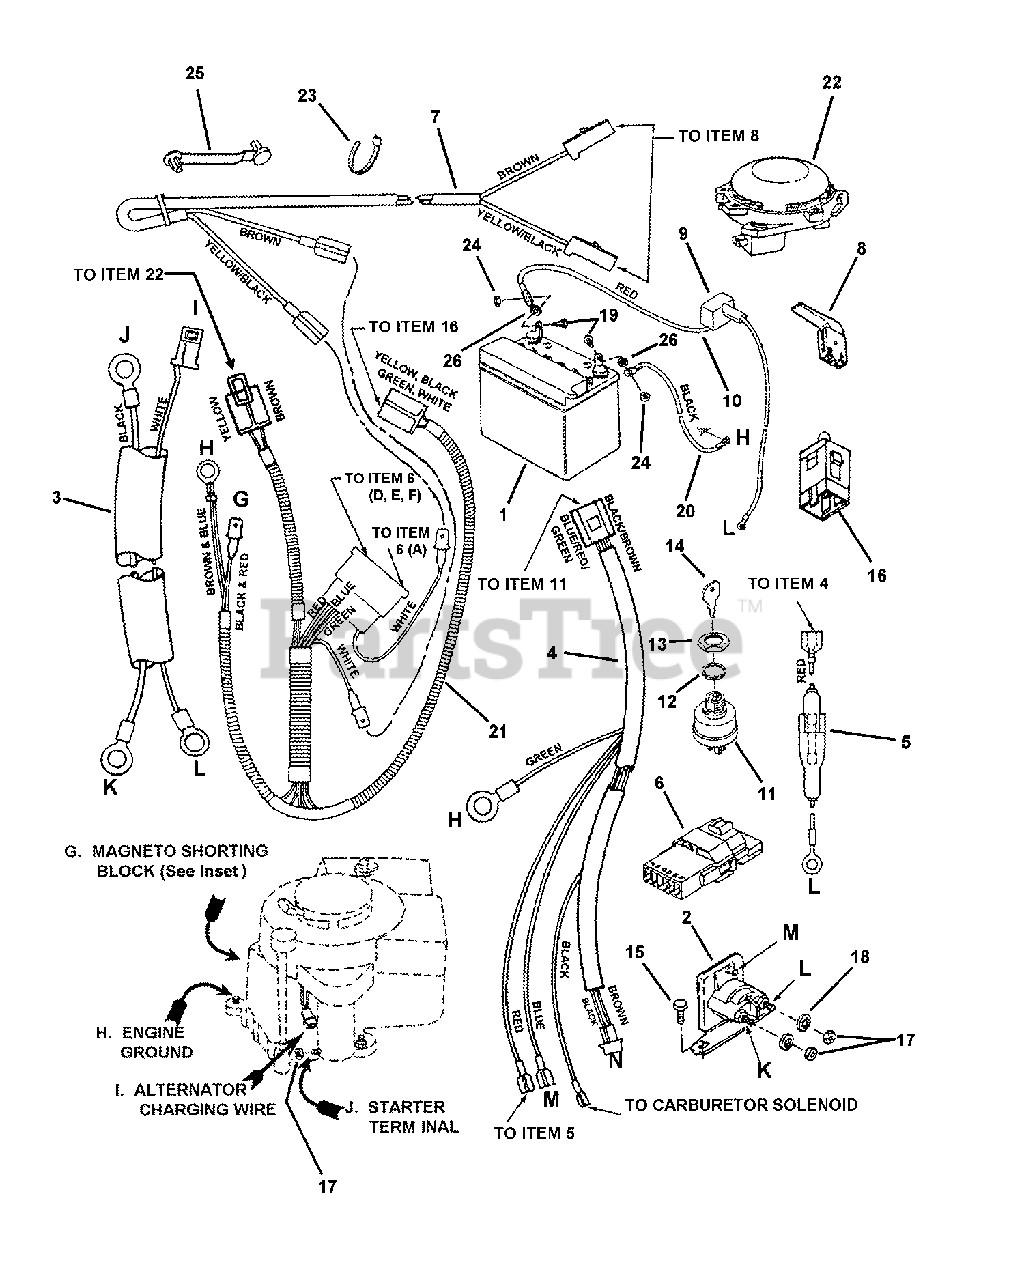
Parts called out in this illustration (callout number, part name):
1	KIT, Battery, 12V, U-1-7RS, 220CCA Dry Charge Snapper No Spill
2	SOLENOID, Super-Trombetta
3	HARNESS, Starter Wiring (Briggs Engines)
4	HARNESS, Ignition Wiring (Briggs)
5	HOLDER, Fuse (Includes Fuse)
6	INTERLOCK MODULE, Briggs
7	HARNESS, (Deck Interlock Wiring)
8	SWITCH, Deck Interlock (NO)
9	COVER, Battery Cable
10	WIRE, Positive (Red, 17" long)
11	SWITCH, Ignition-Afterfire Solenoid
12	WASHER, 5/8" Internal Tooth Lock
13	NUT, 5/8-32 Hex
14	KEYS, Blister Pk (KIDS+MWRS DON'T MIX) English/Spanish (set of two, one coated)
15	SCREW, 1/4-20 x 1/2" Hex Washer Self-Tap
16	SWITCH, Operator Presence Control (OPC) Traction (NC/NO)
17	NUT, 1/4-20 Hex, GR 5 or B
18	WASHER, 1/4" Internal Tooth Lock
19	SCREW, 1/4-20 x 5/8" Hex Head Cap GR 5
20	WIRE, Negative, Black (15" long)
21	HARNESS WIRE, Operator Presence Control (OPC)
22	SWITCH, Seat (NC)
23	CABLE TIE, 7"
24	NUT, 1/4-20 Hex Center Lock, GR 5 or B
25	CABLE TIE, 7"
26	RETAINER, 1/4" Bolt
